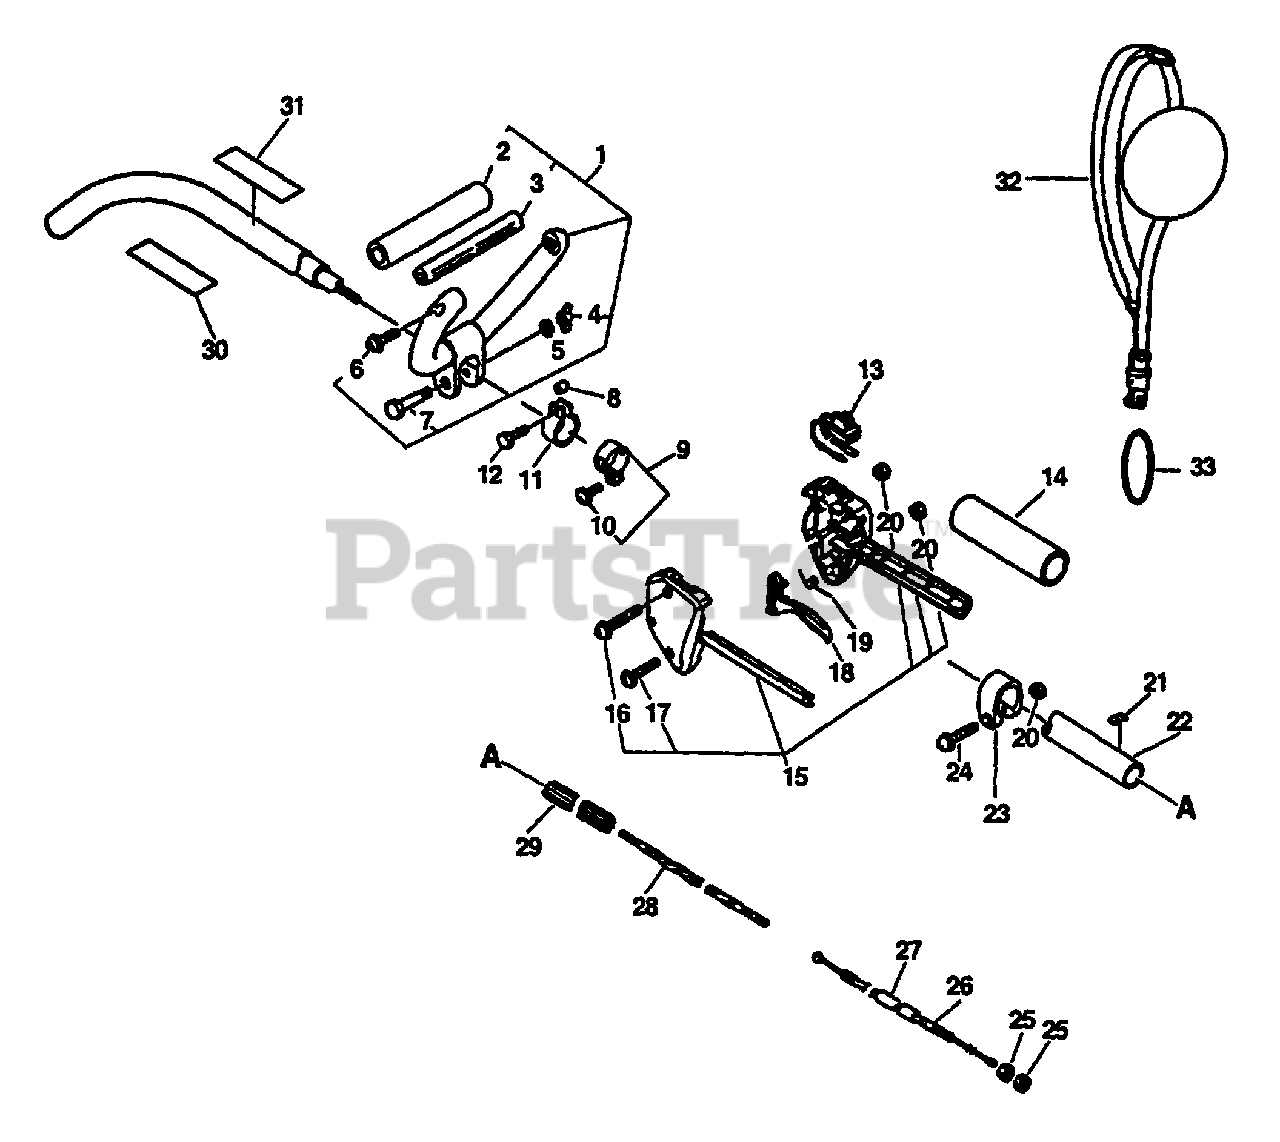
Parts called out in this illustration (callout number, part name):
1	LOOP HANDLE ASSY
2	GRIP, HANDLE
4	NUT, WING 6
5	WASHER 6.5×11.5×0.8
6	SCREW 5×30
7	BOLT - 6×40
8	SPACER, GUARD
9	CLAMP KIT
10	SCREW 5×14
12	BOLT 5×18
13	IGNITION SWITCH ASSY
14	GRIP, HANDLE
15	THROTTLE BRACKET SET
16	SCREW 5×35
17	SCREW 5×25
18	TRIGGER, THROTTLE
19	SPRING, TORSION
20	NUT M5
21	LABEL - ALIGNMENT
22	MAIN PIPE ASSY
24	SCREW 5×28
26	CABLE, THROTTLE
28	DRIVESHAFT - FLEXIBLE
29	LINER - FLEXIBLE
30	LABEL, CAUTION
31	LABEL, CAUTION
32	SHOULDER STRAP ASSY
33	RING, HARNESS Ø32
